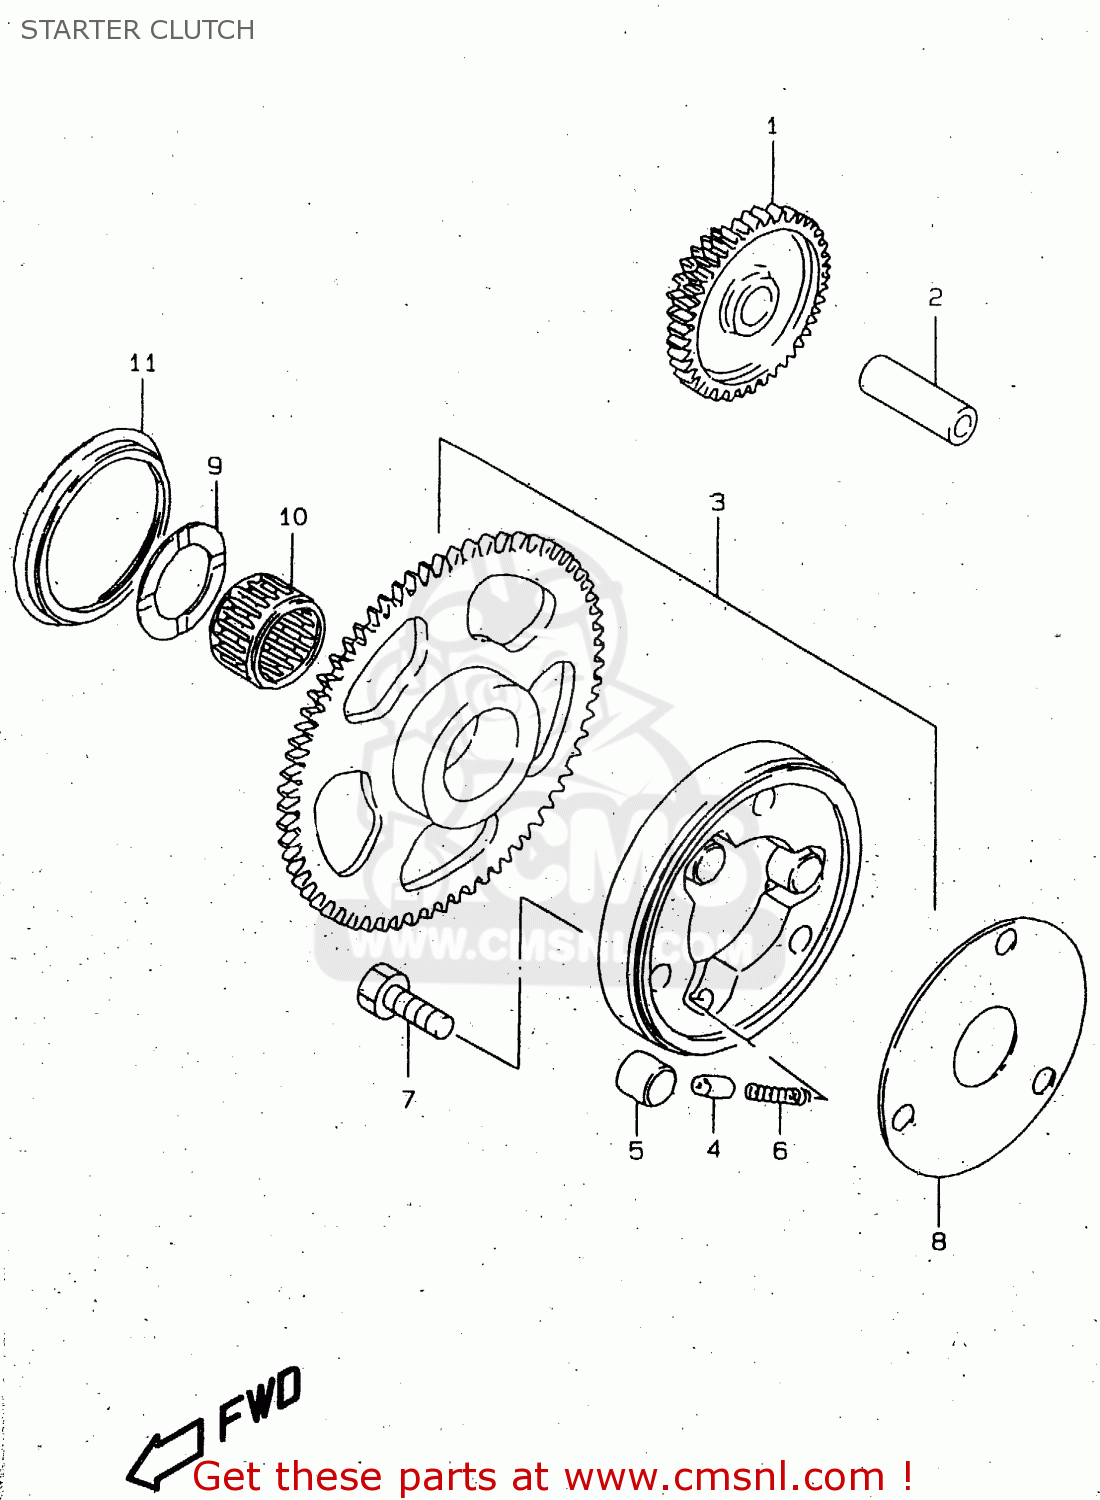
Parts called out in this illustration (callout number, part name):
1	GEAR,STARTER IDLE
2	PIN(7.4X13X40)
3	CLUTCH SET,STARTER
4	PIECE,PUSH
5	PIN(14X13)
6	SPRING
7	BOLT
8	SHIM,STARTER CLUTCH HUB
9	WASHER(27X40X2.5)
10	BEARING(27X32X21.8)
11	SEAL,OIL(52X62X6.8)
